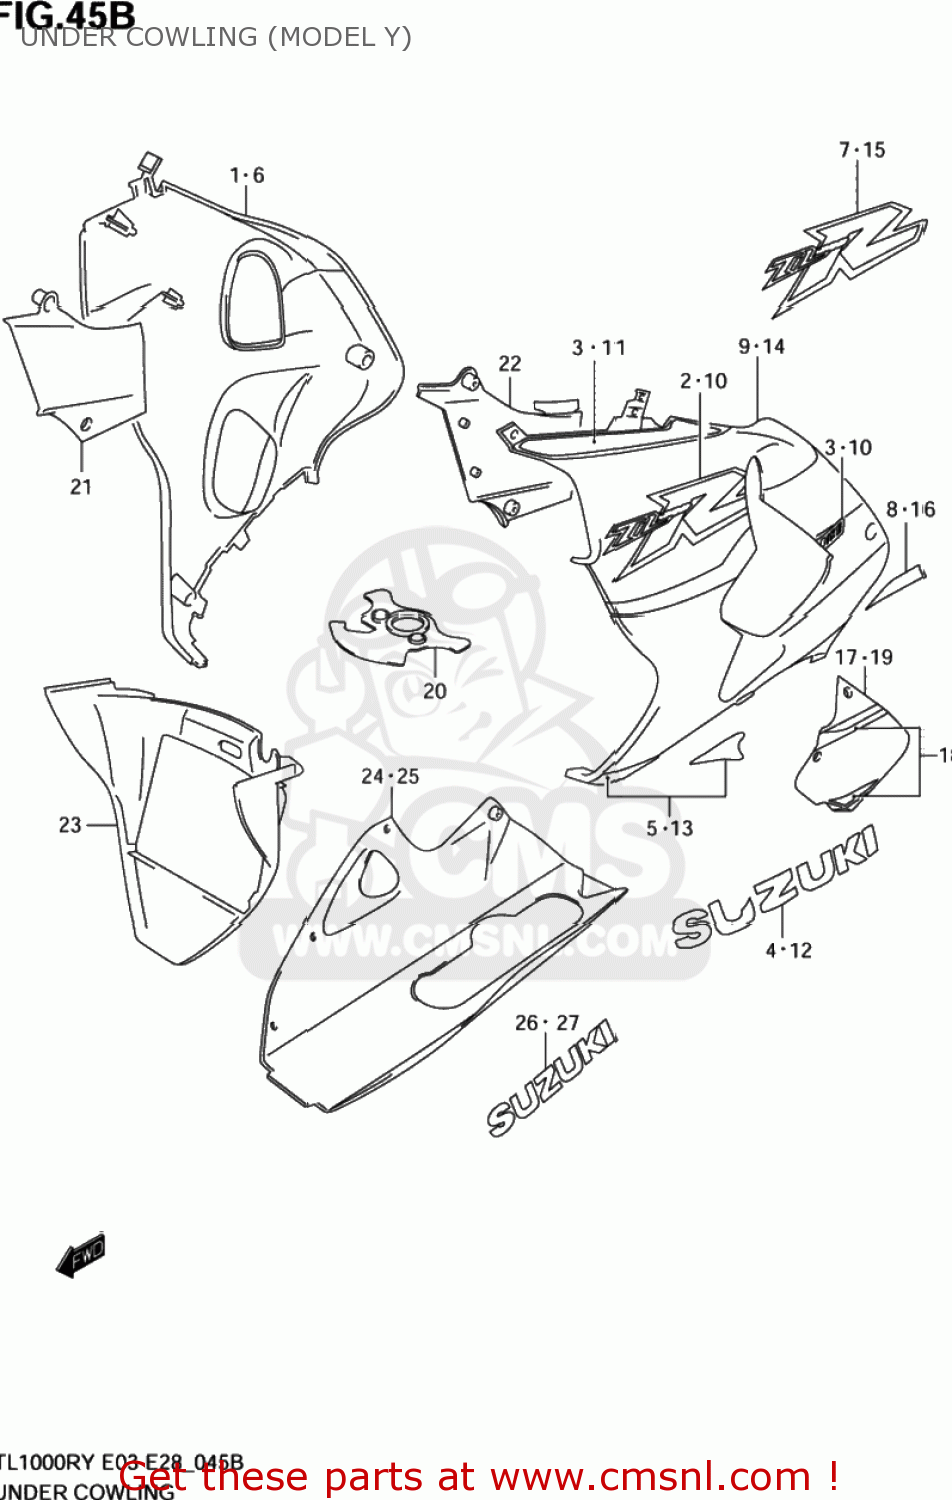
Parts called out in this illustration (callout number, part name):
1	COWLING ASSY,UNDER,R
2	EMBLEM,TL1000R
3	TAPE,COWL UNDER UPR,R
4	EMBLEM,SUZUKI,R
5	TAPE SET,UNDER,R
6	COWLING ASSY,UNDER,R
7	EMBLEM,COWLING UNDER,R
8	TAPE,COWL UNDER LWR,R
9	COWLING ASSY,UNDER,L
10	EMBLEM,TL1000R
11	TAPE,COWL UPR,L
12	EMBLEM,SUZUKI,L
13	TAPE SET,UNDER,L
14	COWLING ASSY,UNDER,L
15	EMBLEM,COWLING UNDER,L
16	TAPE,COWL UNDER LWR,L
17	LID ASSY,COWL UNDER,L
18	TAPE,LID COWL UNDER,L
19	LID,COWL UNDER,L(YELLOW)
20	COVER,LWR BRACKET
21	COWLING,UNDER INNER,R
22	COWLING,UNDER INNER,L
23	COWLING,UNDER CTR
24	COWLING,UNDER RR
25	COWLING ASSEMBLY,UNDER,REAR (S
26	EMBLEM,COWLING UNDER RR
27	EMBLEM,COWLING UNDER RR,L
